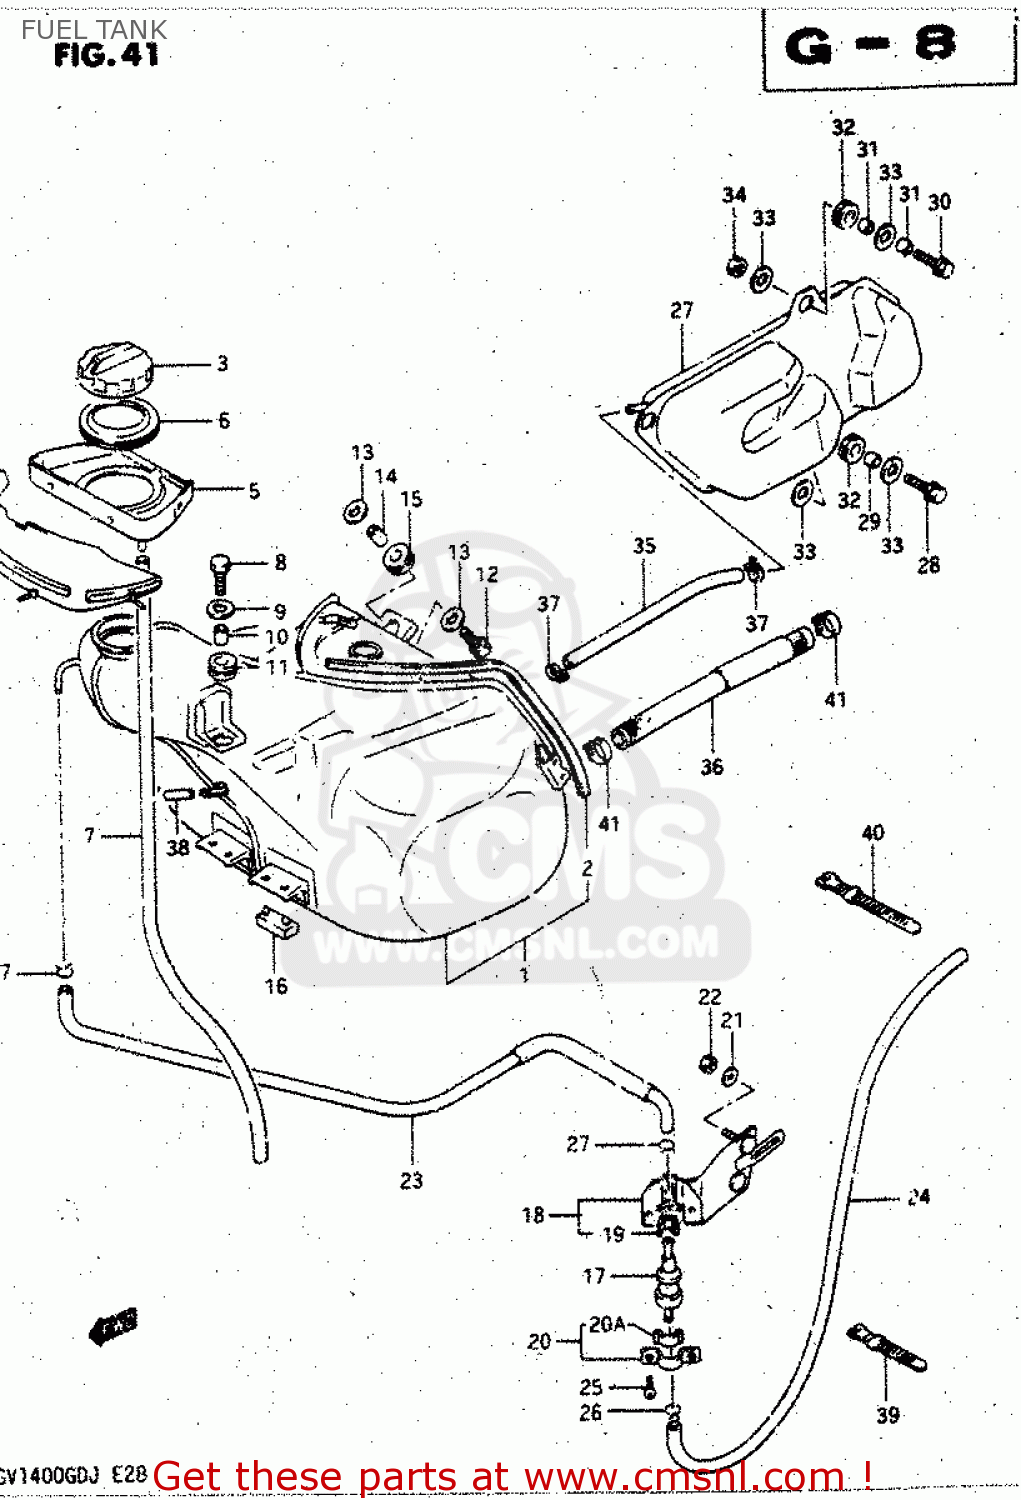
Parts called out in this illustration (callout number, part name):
1	TANK ASSEMBLY,FUEL
2	MOLDING, NO.2
3	CAP ASSEMBLY,FUEL TANK
4	COVER,FUEL INLET TRAY
5	TRAY, FUEL INLET
6	JOINT,FUEL INLET,TRAY
7	HOSE
8	BOLT,M6X1X20
9	WASHER
10	SPACER(6.1X9X7.5)
11	CUSHION
12	BOLT
13	WASHER (8.5X29X1.6)
14	SPACER (8.6X13.8X8)
15	CUSHION
16	CUSHION
17	VALVE,FUEL TANK BREATHER
18	PLATE,FUEL TANK BREATHER
19	CUSHION
20	PLATE,FUEL TANK BREATHER NO.2
20A	CUSHION
21	WASHER(6.5X18X1)
22	NUT 6MM
23	HOSE
24	HOSE
25	SCREW
26	(CA) CLIP
27	SUB TANK,FUEL
28	BOLT
29	SPACER (8.8X12X11)
30	BOLT 8X40
31	SPACER(8.4X12X12)
32	CUSHION
33	WASHER
34	NUT
35	HOSE
36	HOSE, BREATHER
37	CLAMP
38	HOSE
39	CLAMP(L:125)
40	CLAMP(L:187)
41	CLAMP
